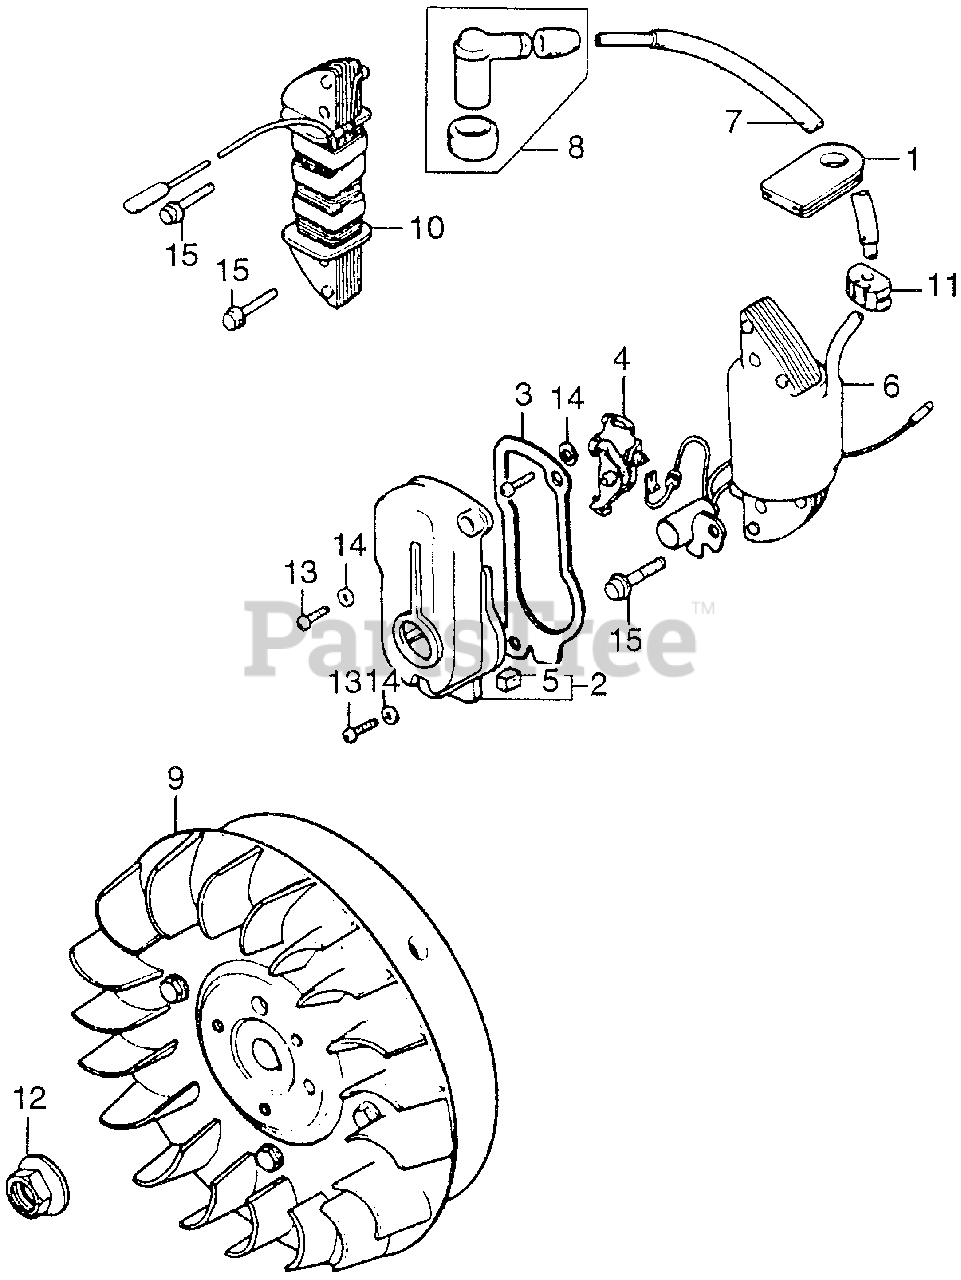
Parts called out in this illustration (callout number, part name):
1	GROMMET, WIRE
2	COVER ASSY., POINTS (NOT AVAILABLE)
3	GASKET, POINT COVER (NOT AVAILABLE)
4	POINTS ASSY.
5	FELT, OIL
6	COIL ASSY., IGNITION (DENSO) (NOT AVAILABLE)
7	TUBE, IGNITION RUBBER
8	TERMINAL ASSY., IGNITION
9	FLYWHEEL ASSY.
10	LAMP COIL ASSY.
11	GROMMET, WIRE
12	NUT, SPECIAL (14MM)
13	SCREW, PAN (4X8)
14	WASHER, PLAIN (4MM)
15	BOLT, FLANGE (6X25) (NOT AVAILABLE)
